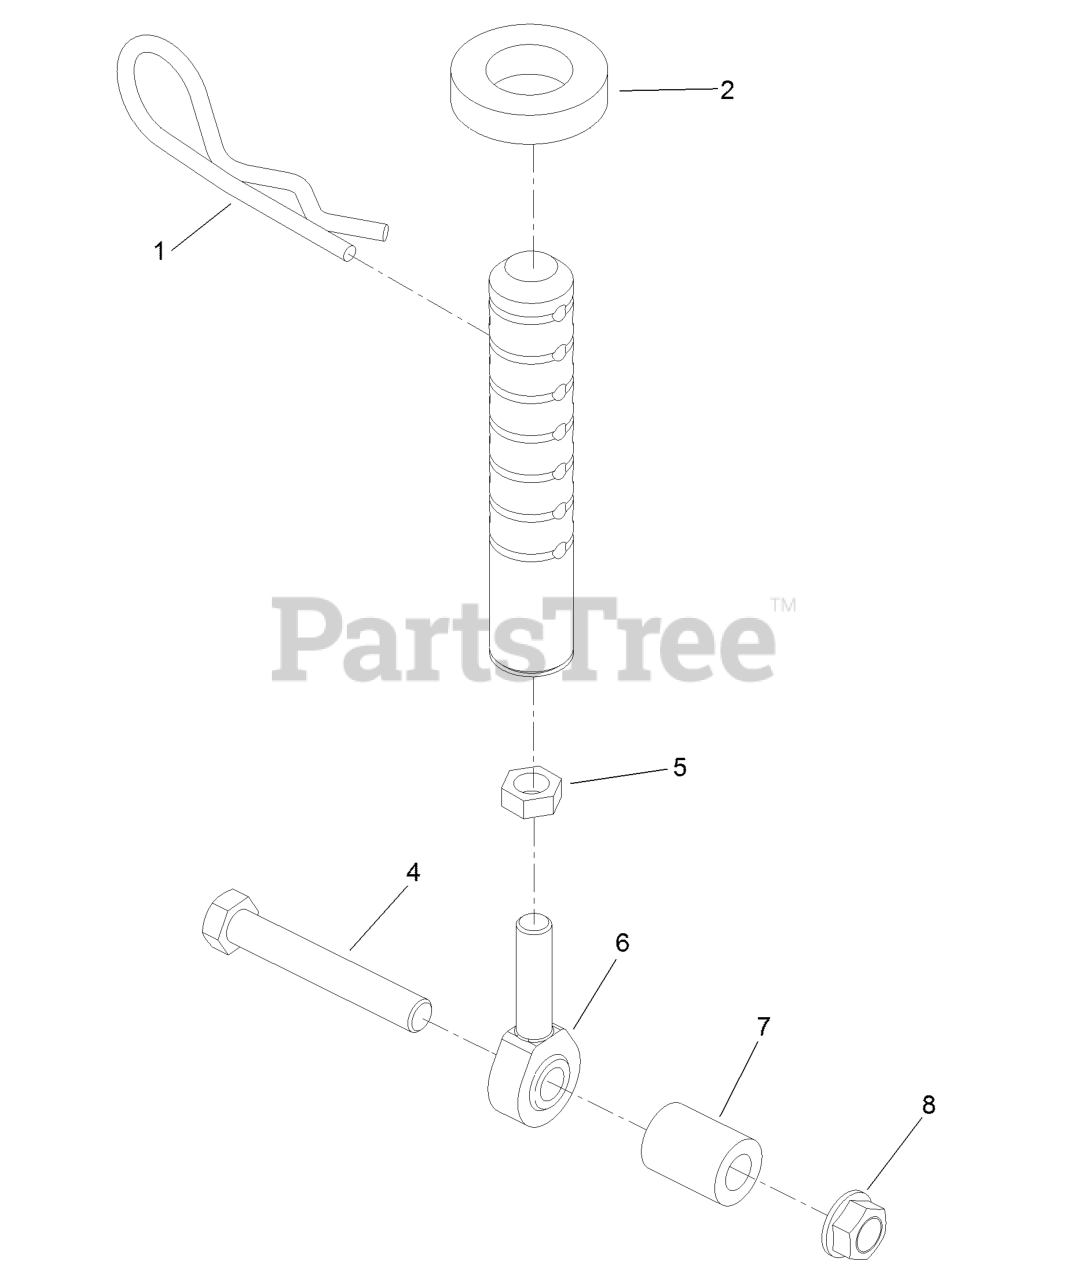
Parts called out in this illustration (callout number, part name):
1	Pin-Cut Height
2	Spacer-Deck Support
4	Screw-HH
5	Nut-HJ
6	Balljoint
7	Tube-Interlock
8	Nut-HHF, Whiz
